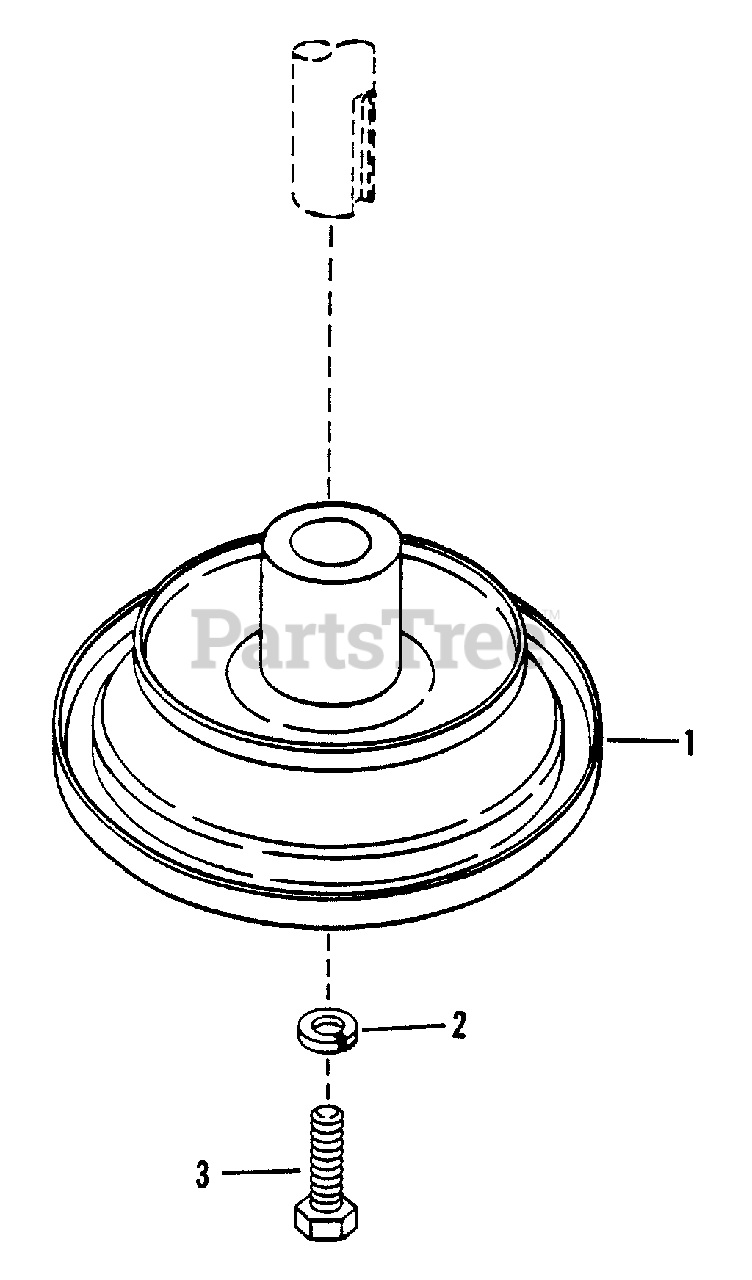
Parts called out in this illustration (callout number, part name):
1	ASSEMBLY, Drive Disc
2	WASHER, 7/16 Internal Tooth Lock
3	SCREW, 7/16-20 x 1" Hex Head Cap
